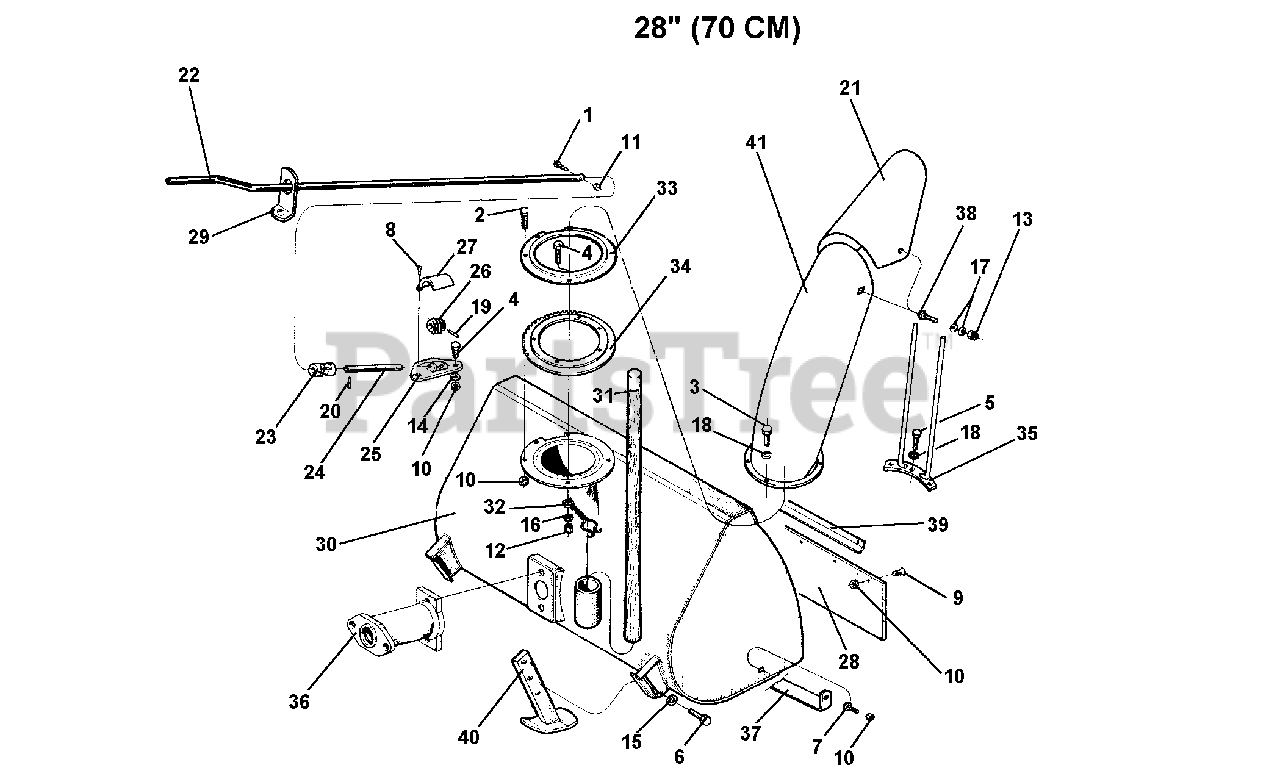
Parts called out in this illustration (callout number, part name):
1	SCREW TE M4 X 35
2	SCREW TE M6 X 14
3	SCREW M6 X 12
4	SCREW M6 X 25
5	SCREW TE M6 X 16
6	SCREW TE M10 X 16 UNI 5739-8G
7	SCREW M6 X 20
8	SCREW TSVEI M5 X 10
9	SCREW M6 X 16
12	NUT, SELF LOCKING M6
13	NUT, SELF LOCKING M10
14	WASHER, FLAT 6.4
15	FLAT WASHER 10.5 X 21
16	WASHER FLAT 6.4
17	SPRING 10.2 X 28 X 1.5
18	WASHER, LOCK 6.4
19	PIN, LOCKING 4 X 25
20	PIN, LOCKING 5 X 30
22	FUNNEL CONTROL ROD
26	HELICAL GEAR
28	SPRAY PROTECTION
29	ROD SUPPORT FOR SNOW THROWER 70 CM
31	VERTICAL STICK
32	SPRING FOR STICK
33	FLANGE FOR RING
35	GRID FOR CHUTE 1985
36	P.T.O. COUPLING
37	COVER SKID 70 CM
38	SCREW M10 X 25
39	MUDFLAP HOLDER
